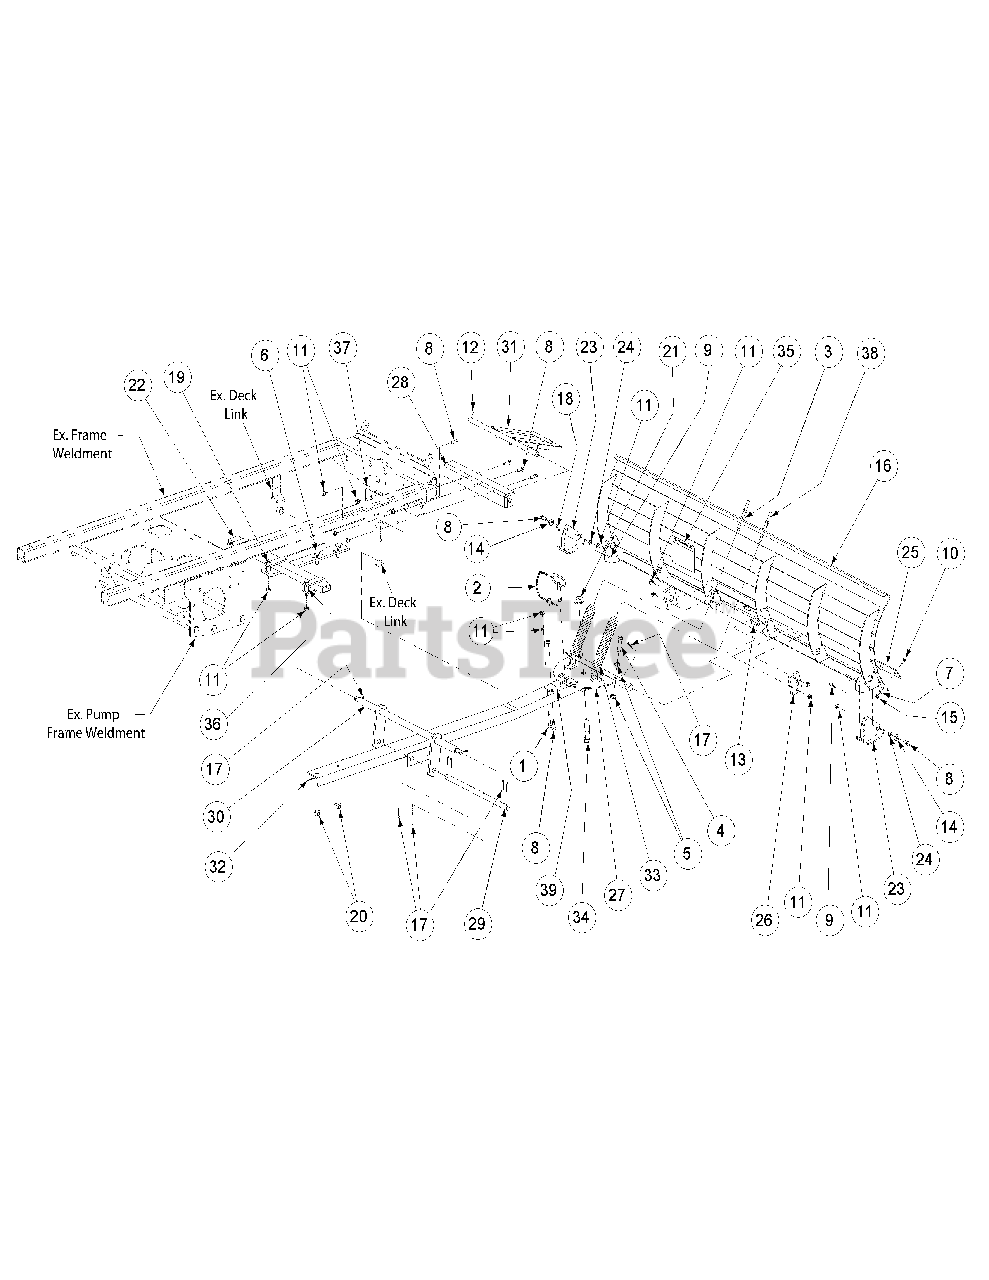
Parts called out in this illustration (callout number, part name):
1	Hex Cap Screw:3/8-16 x 1.75
2	Sulky Pin
3	Hex Nut 3/8-16
4	Hex Cap Screw:1/2-13 x 2.0
5	Hex Nut:1/2-13
6	Hex Cap Screw:1/2-13 x 1.50
7	Washer:5/16
8	Hex Cap Screw:3/8-16 x 1.0
9	Clevis Pin:5/16 x 1.0
10	Carriage Bolt:5/16-18 x .75
11	Flange Lock Hex Nut, 3/8-16
12	Cotter Pin:1/8 x 1.0:SS
13	Hex Cap Screw, 3/8 -16 x 1.25
14	Washer, .385 x 1.0 OD x .135
15	Hex Flange Lock Nut, 5/16-18
16	Snow Blade Weldment
17	Cotter Pin, 5/32, 1.25
18	Cotter Pin, .072 x 1.12 Lg
19	Hex Cap Screw:3/8-16 x 2.0
20	Flange Lock Nut, 1/2-13
21	Nut, 3/4-16, Hex Flange
22	Rear Support Weldment
23	Skid Plate Weldment
24	Skid Plate Spacer
25	Snow Blade
26	Rod Bearing Pivot Plate
27	Pivot Blade Weldment
28	Front Stabilizer Bracket Weldment
30	Lift Rod Weldment
31	Bracket Guide Weldment
32	Channel Support Weldment
33	Spring, Blade Adjust
34	Hex Cap Screw, 3/8-16 x 3.00
35	Label, Warning
36	Rear Support Spacer
37	Front Stabilizer Plate
38	Bolt:3/8-16 x 4.50
39	Retainer Pin Bracket
